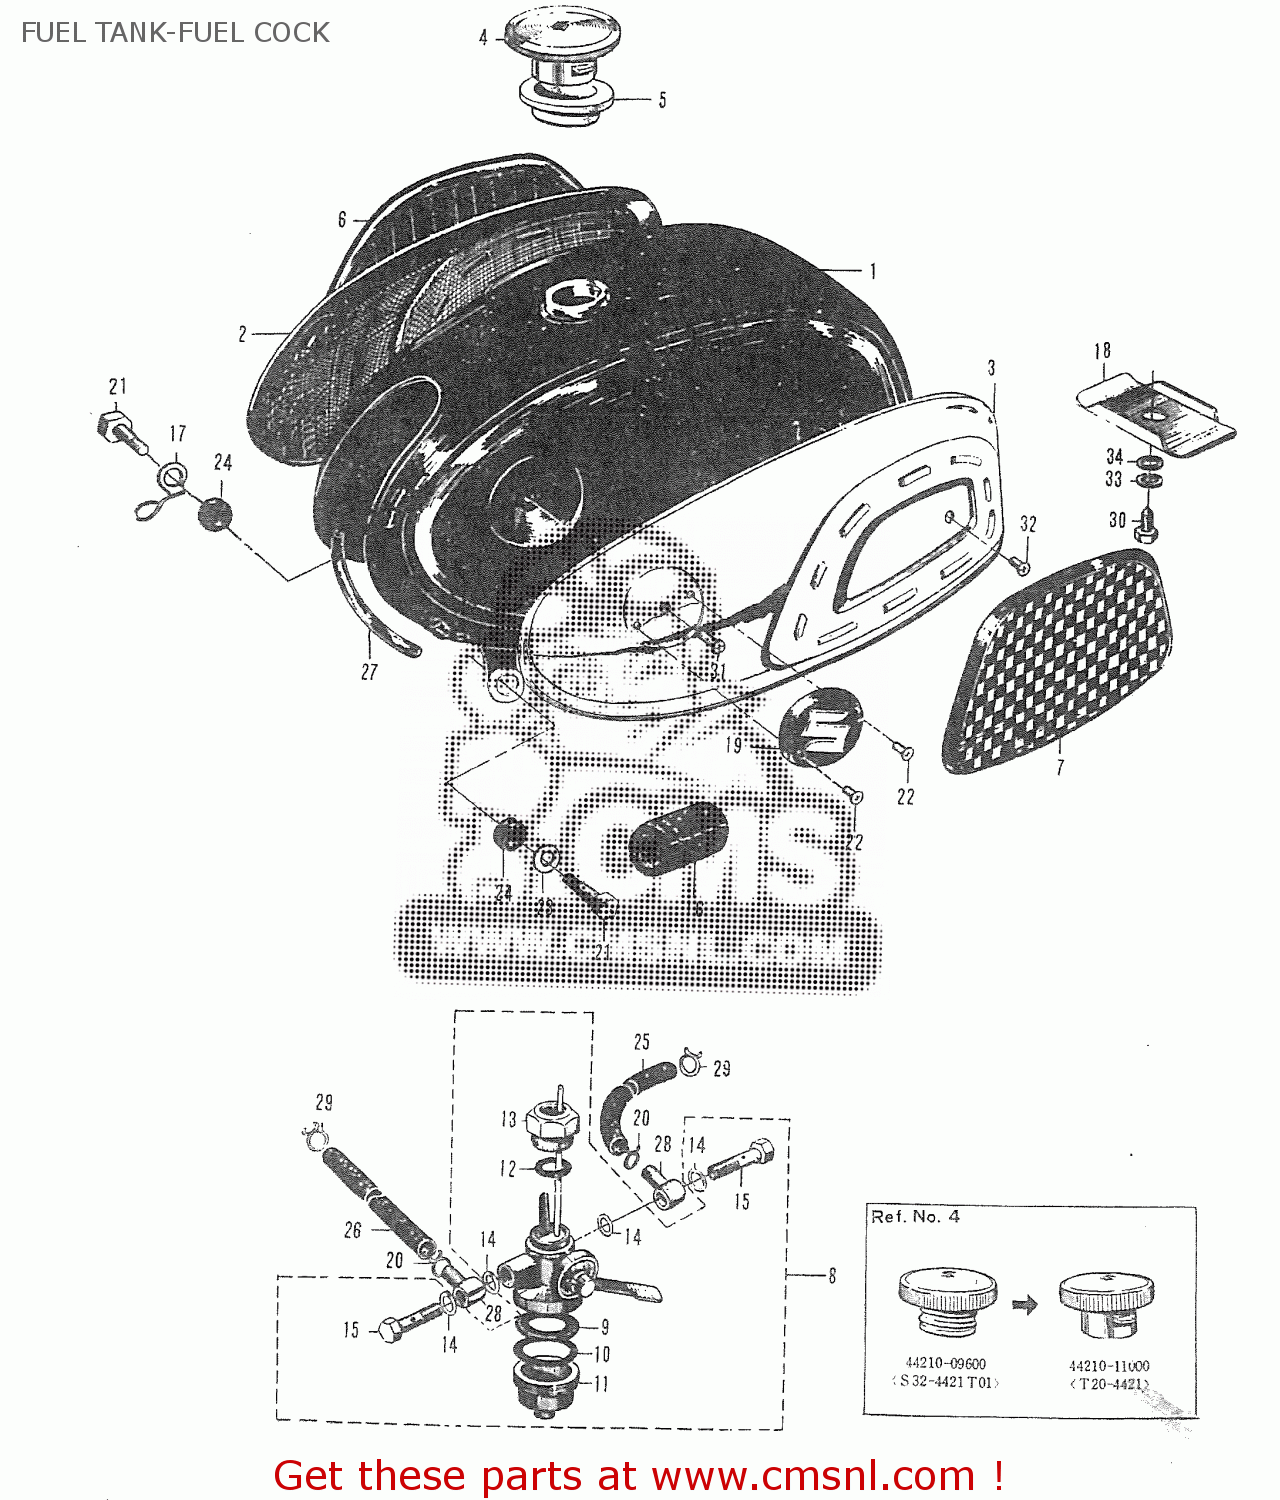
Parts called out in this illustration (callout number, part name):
1	FUEL TANK
2	FUEL TANK RIGHT SIDE COVER
3	FUEL TANK LEFT SIDE COVER
4	FUEL TANK CAP
5	GASKET,FUEL TANK CAP (NAS)
6	RIGHT KNEE GRIP
7	LEFT KNEE GRIP
8	FUEL COCK ASS'Y
9	FUEL COCK STRAINER FILTER NET
10	FUEL COCK STRAINER CUP GASKET
11	FUEL COCK STRAINER CUP
12	FUEL COCK GASKET
13	FUEL COCK JOINT NUT
14	FUEL COCK UNION BOLT GASKET
15	FUEL COCK UNION BOLT
16	FUEL TANK REAR MOUNTING SHOCK DAMPER
17	FUEL TANK FRONT RIGHT FITTING WASHER
18	FUEL TANK REAR MOUNTING BRACKET
19	EMBLEM
20	FUEL LINE CLIP
21	FUEL TANK FRONT MOUNTING BOLT
22	FUEL TANK EMBLEM FITTING SCREW
23	WASHER
24	CUSHION
25	LEFT FUEL LINE
26	RIGHT FUEL LINE
27	FUEL GAUGE PIPE
28	FUEL LINE CONNECTOR
29	CLIP
30	POINTED SMALL HEAD HEXAGON BOLT
31	CROSS HEAD SCREW
32	CROSS HEAD SCREW
33	LOCK WASHER
34	SMALL FLAT WASHER
